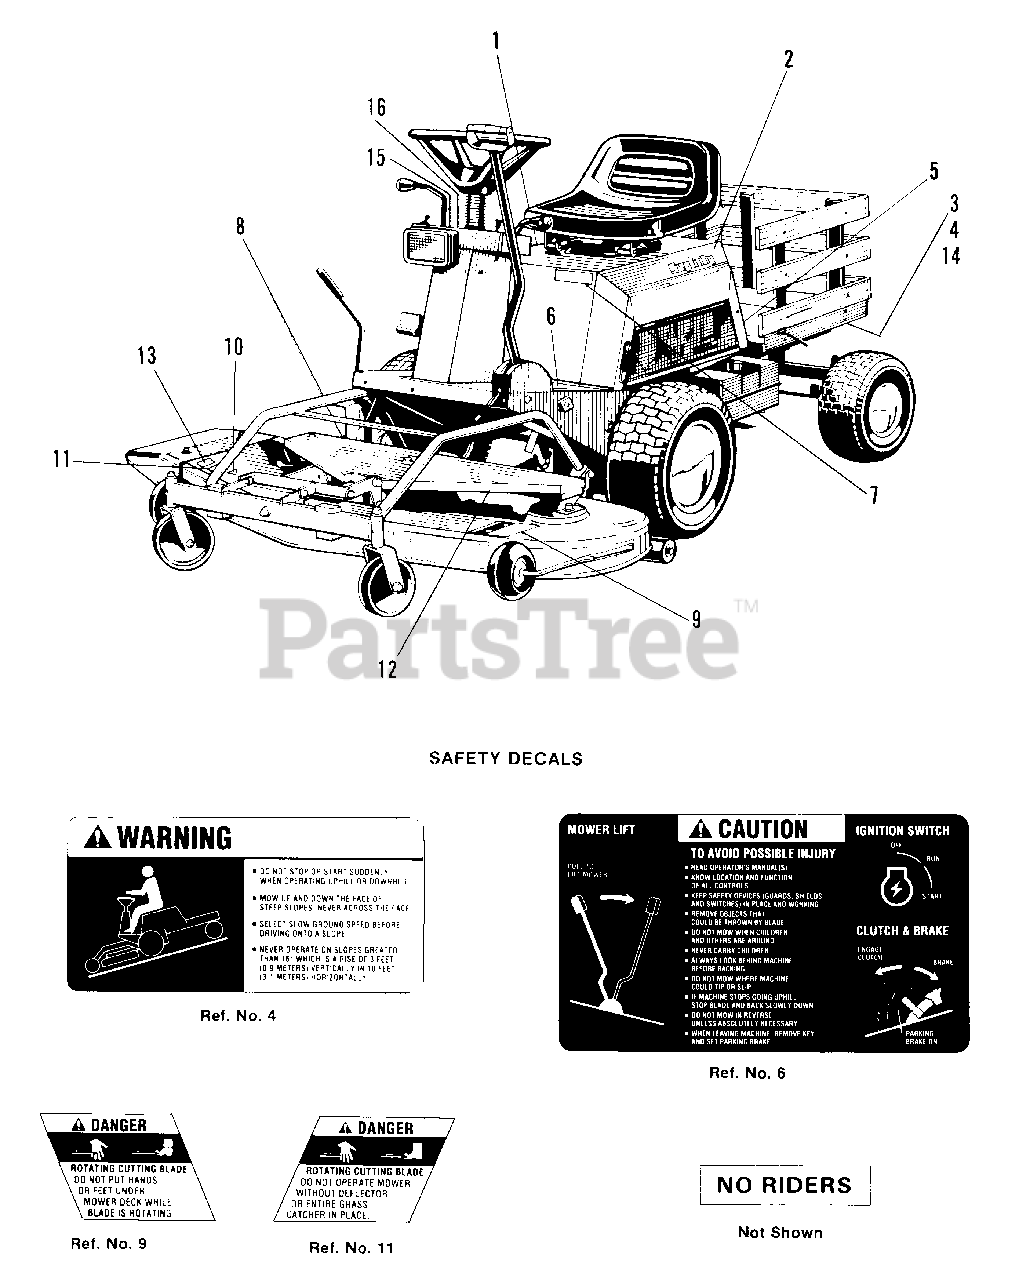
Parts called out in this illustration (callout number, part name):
1	DECAL, Side, R.H., 12 (Simplicity)
1	DECAL, Side, R.H., 12 (Deutz)
2	DECAL, Side, L.H., 12 (Simplicity)
2	DECAL, Side, R.H., 12 (Deutz)
3	DECAL, Drive Belts (Simplicity)
3	DECAL, Drive Belts (Deutz)
4	DECAL, Stability
5	TRACTOR I.D. PLATE
6	DECAL, Caution & Controls (12 HP)
7	DECAL, 12 FC
8	MOWER I.D. PLATE
9	DECAL, Danger
10	DECAL, OPEI
11	DECAL, Danger
12	DECAL, Belt Layout (Under Cover)(Simplicity)
12	DECAL, Belt Layout (Under Cover)(Deutz)
13	DECAL, 42"
14	DECAL, Paint
15	DECAL, Instrument Panel
16	DECAL, Oil Light (Simplicity)
16	DECAL, Oil Light (Deutz)
